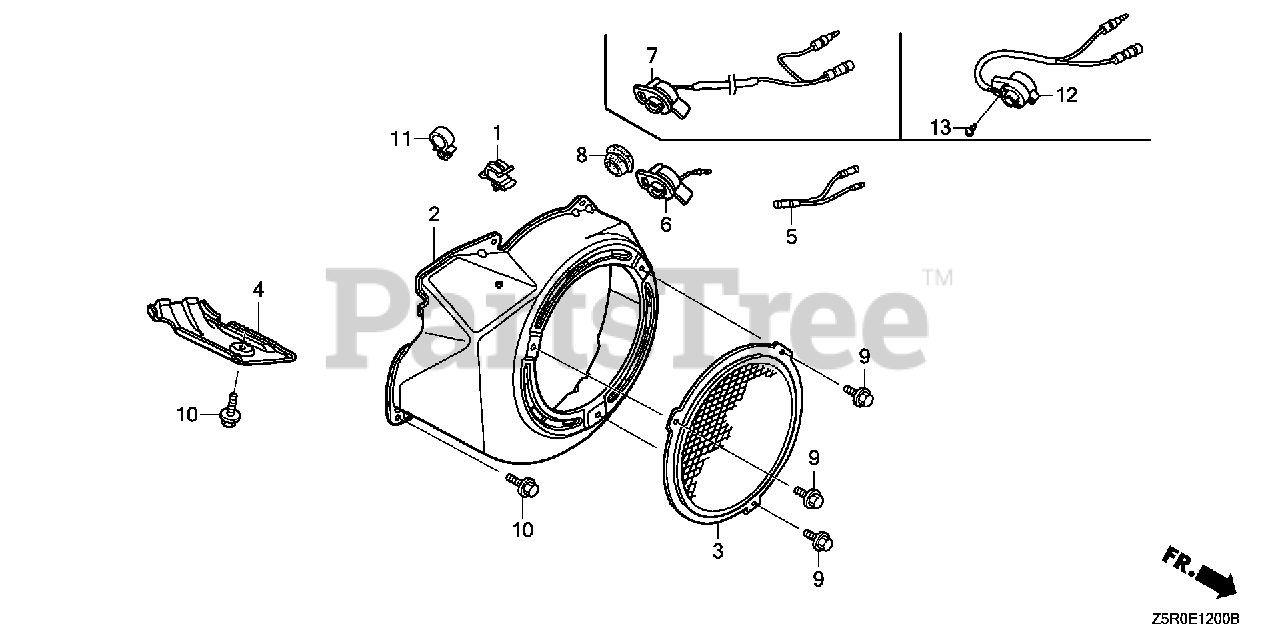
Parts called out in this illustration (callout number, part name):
1	CLIP, TUBE
2	COVER, FAN *R280* (POWER RED)
2	COVER, FAN *NH1* (BLACK)
8	GROMMET, DRAIN HOLE
10	BOLT, FLANGE (6X12) (CT200)
